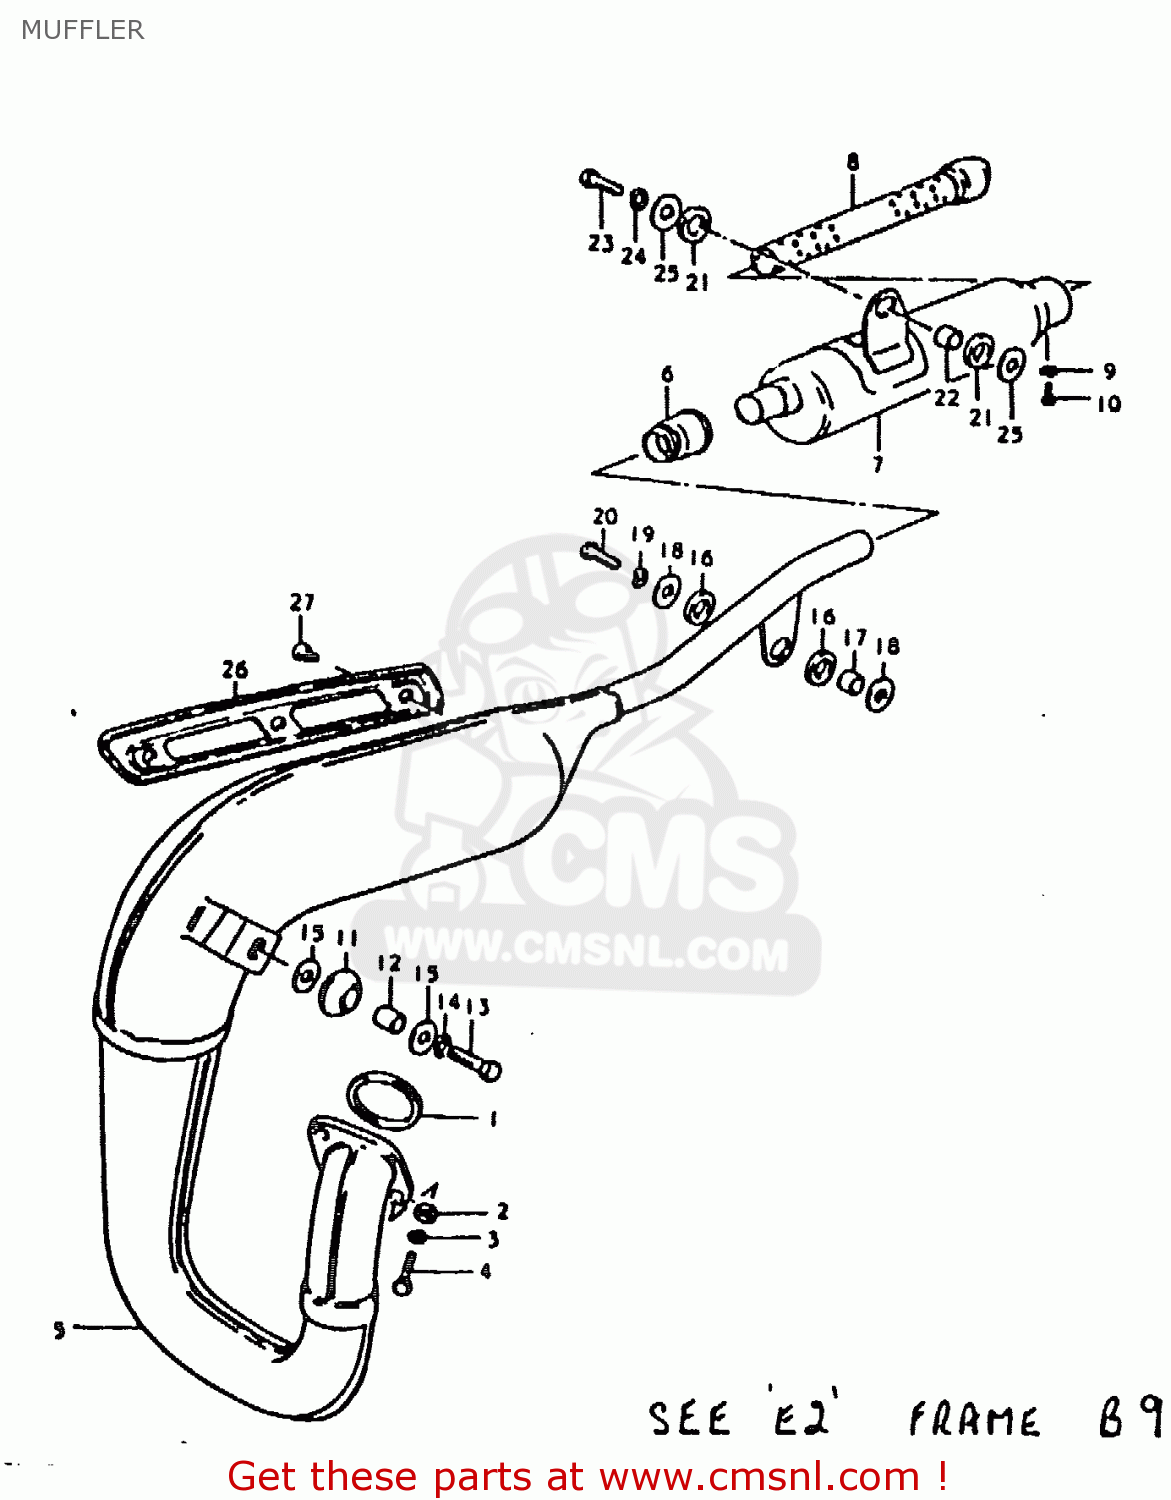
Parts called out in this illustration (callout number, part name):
1	GASKET,EXHAUST PIPE (NAS)
2	WASHER
3	LOCK WASHER
4	SCREW
5	BODY,MUFFLER
6	CONNECTOR,MUFFLER
7	MUFFLER ASSY, 2ND
8	PIPE,BAFFLE
9	LOCK WASHER
10	SCREW
11	DAMPER,MUFFLER,FR
12	SPACER (8X12X15)
13	BOLT
14	LOCK WASHER
15	WASHER (8.7X22X2)
16	CUSHION
17	SPACER (8.6X13.8X9.8)
18	WASHER
19	LOCK WASHER
20	BOLT
21	CUSHION
22	SPACER (8.6X13.8X9)
23	BOLT
24	LOCK WASHER
25	WASHER
26	COVER,MUFFLER
27	SCREW
